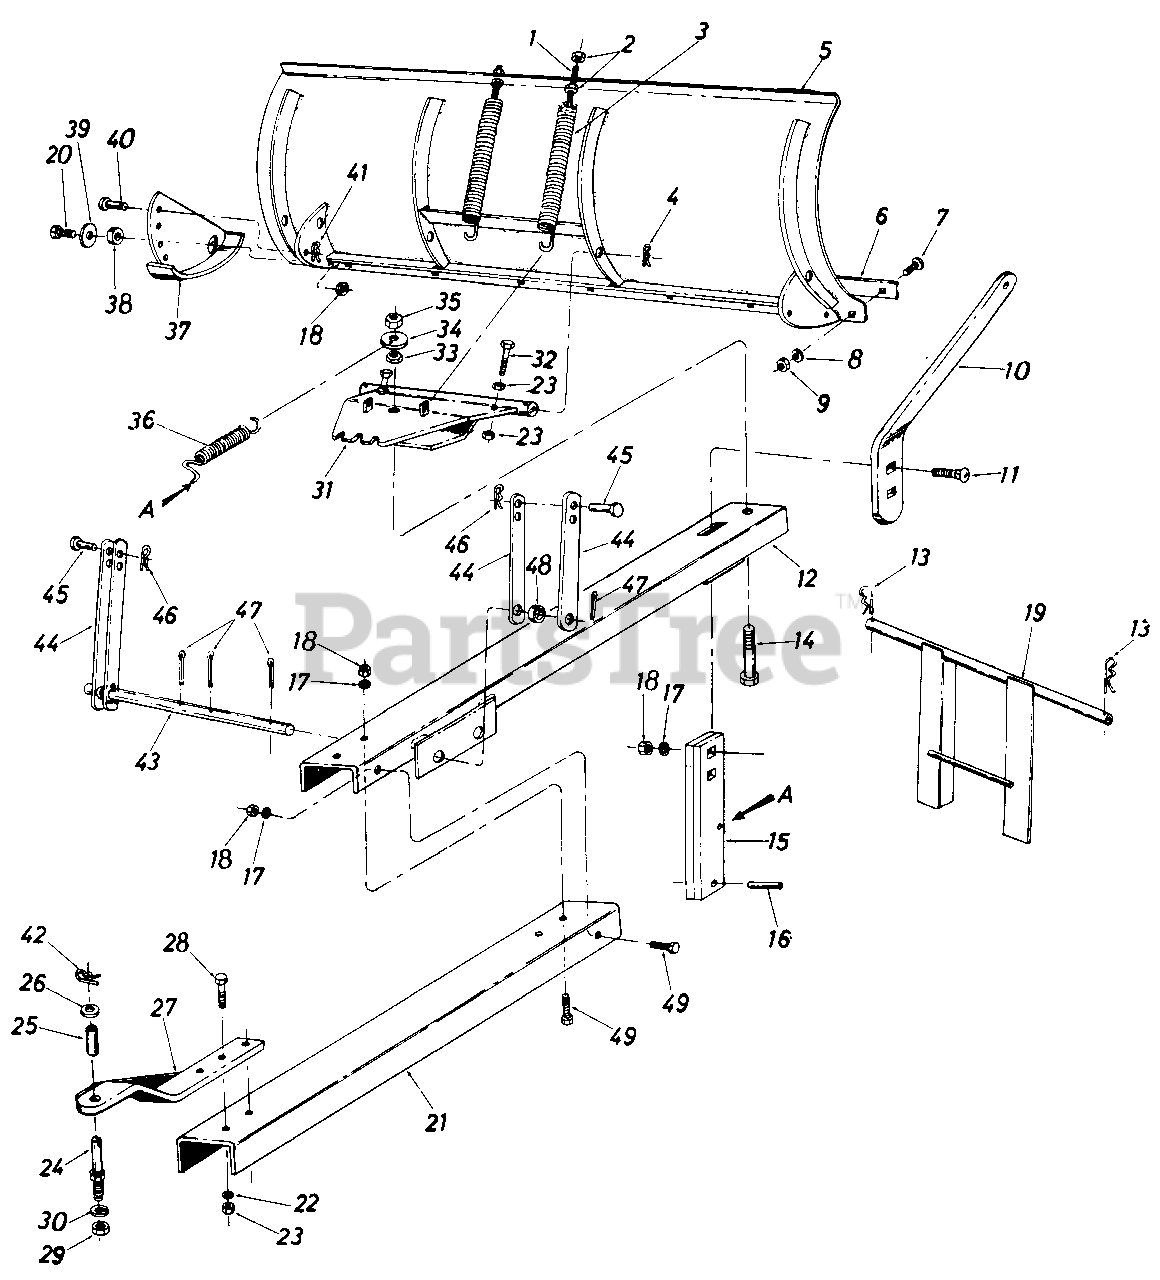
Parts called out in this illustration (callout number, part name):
1	Hex Scr. 3/8-16 x 4.50" Lg.*
2	Hex Nut 3/8-16 Thd.*
3	Blade Adjustment Spring
4	Hair Pin Cotter, 5/32
5	54" Blade Ass'y.
6	Wear Plate
7	Carriage Bolt 5/16-18 x .75" Lg.*
8	L.-Wash. 5/16" Scr.*
9	Hex Nut 5/16-18 Thd.*
10	Lock Extension Bar
11	Carriage Bolt 3/8-16 x 1.25" Lg.*
12	Front Push Bar Ass'y.
13	Hair Pin Cotter, 5/32
14	Hex Scr. 3/4-10 x 3.50" Lg.*
15	Angle-Lock Bar
16	Spring Pin Spirol .25" Dia. x 1.00" Lg.
17	L.-Wash. 3/8" Scr. *
18	Hex L.-Nut 3/8-16 Thd.*
19	Guide Bracket Ass'y.
20	Hex Scr. 3/8-16 x .75" Lg.*
21	Rear Push Bar Channel
22	L.-Wash. 1/2" Scr.*
23	Hex Nut 1/2-13 Thd.*
24	Link Clevis Pin
25	Spacer l" O.D. x 21/32" I.D. x .75" Lg.
26	Fl-Wash. 21/32 I.D. x .090 O.D.
29	Hex Jam L.-Nut 5/8-18 Thd.
30	L.-Wash. 5/8" Scr.*
31	Pivot Plate Ass'y.
32	Hex Scr. 1/2-13 x 2.00" Lg.*
33	Hex Jam Nut 3/4-10 Thd.
34	Fl.-Wash. 3/8"
35	Hex Lock Nut 3/4-10Thd.
36	Angle Lock Spring
37	Skid Assembly
38	Bushing, Pivot Skid
39	Fl.-Wash. .385" I.D. x 1.00" O.D.
40	Clevis Pin 5/16" Dia. x 3/4" Lg.
41	Hair Pin Cotter 3/32"
42	Hair Pin Cotter, 5/32
45	Clevis Pin 1/2" Dia. x 1.00" Lg.
46	Hair Pin Cotter, 3/32"
47	Cotter Pin 1/8" Dia. x 1.50." Lg.*
48	Spacer, Lift Link
49	Hex Scr. 3/8-16 x 1.00" Lg.*
